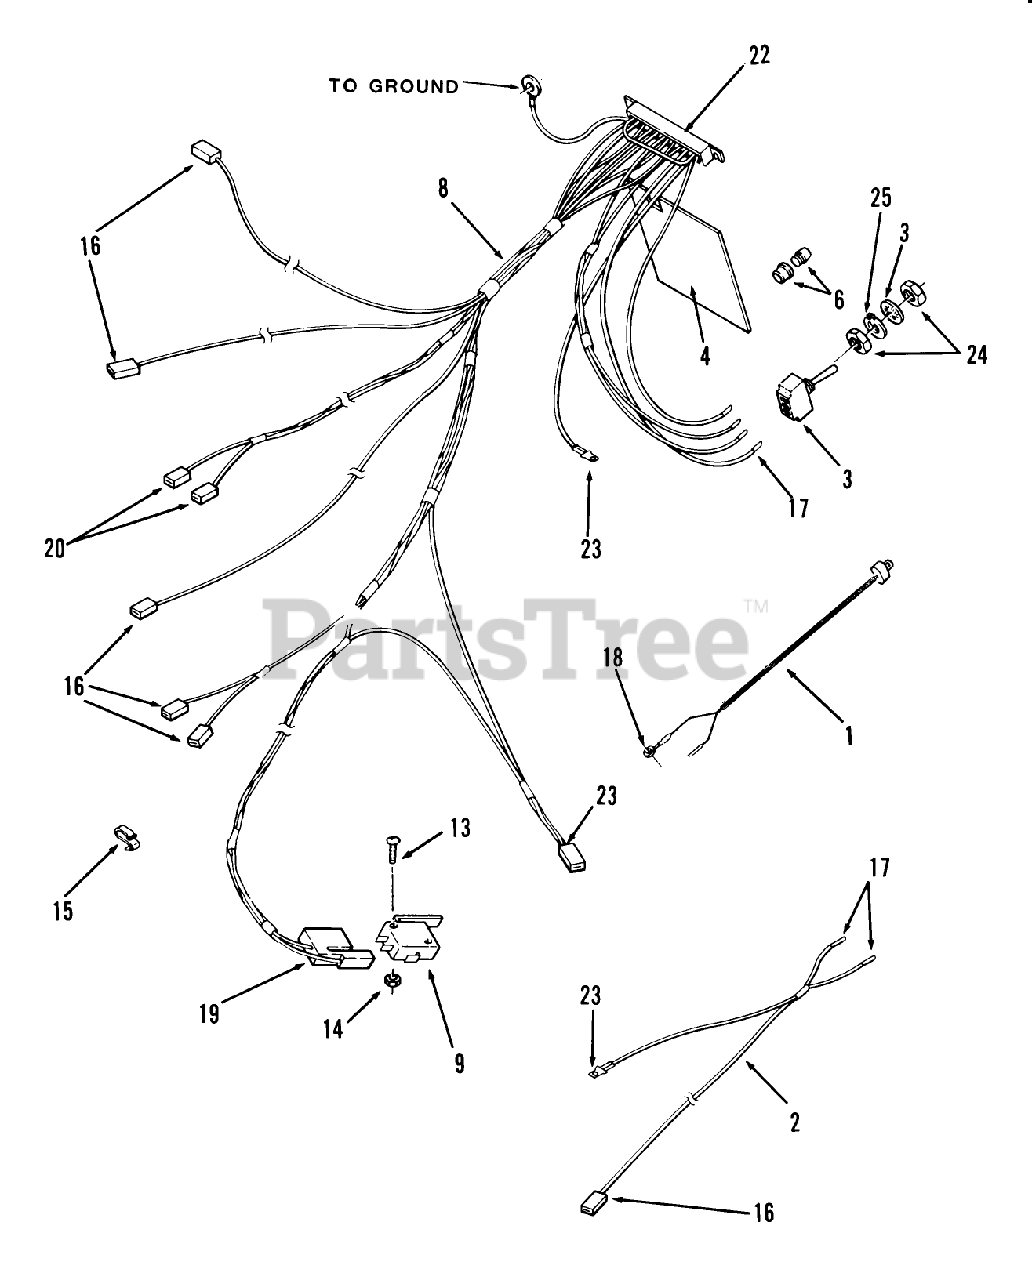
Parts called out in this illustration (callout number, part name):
6	ASSY LENS & BUSHING
8	P.C. BOARD HARNESS
9	SWITCH
15	CLIP-CABLE
16	Piggy-Back Connector (Part of 6)
17	062 X 031 TAB RECEPT
19	CONNECTOR BODY
23	TERMINAL-LONG MALE
24	NUT F/W 116796
